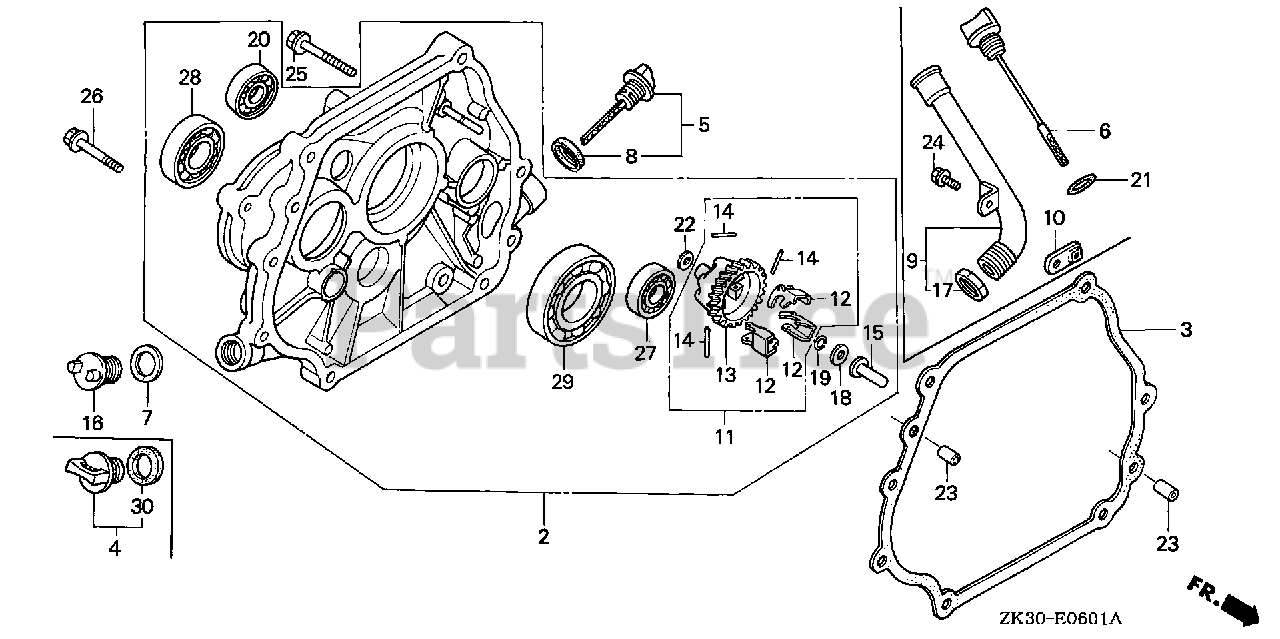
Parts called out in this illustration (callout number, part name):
2	COVER ASSY., CRANKCASE
3	GASKET, CASE COVER
4	CAP ASSY., OIL FILLER
5	CAP ASSY., OIL FILLER
8	GASKET, OIL FILLER CAP
11	GOVERNOR ASSY.
12	WEIGHT, GOVERNOR
13	HOLDER, GOVERNOR WEIGHT
14	PIN, GOVERNOR WEIGHT
15	SLIDER, GOVERNOR
18	WASHER (6X16)
19	CLIP, GOVERNOR HOLDER
20	BEARING, RADIAL BALL (6202) (NTN)
22	WASHER, PLAIN (6MM)
23	PIN, DOWEL (8X12)
25	BOLT, FLANGE (8X40)
26	BOLT, FLANGE (8X40)
27	BEARING, RADIAL BALL (6202)
28	BEARING, RADIAL BALL (6204)
29	BEARING, RADIAL BALL (6207)
30	GASKET, OIL FILLER CAP
